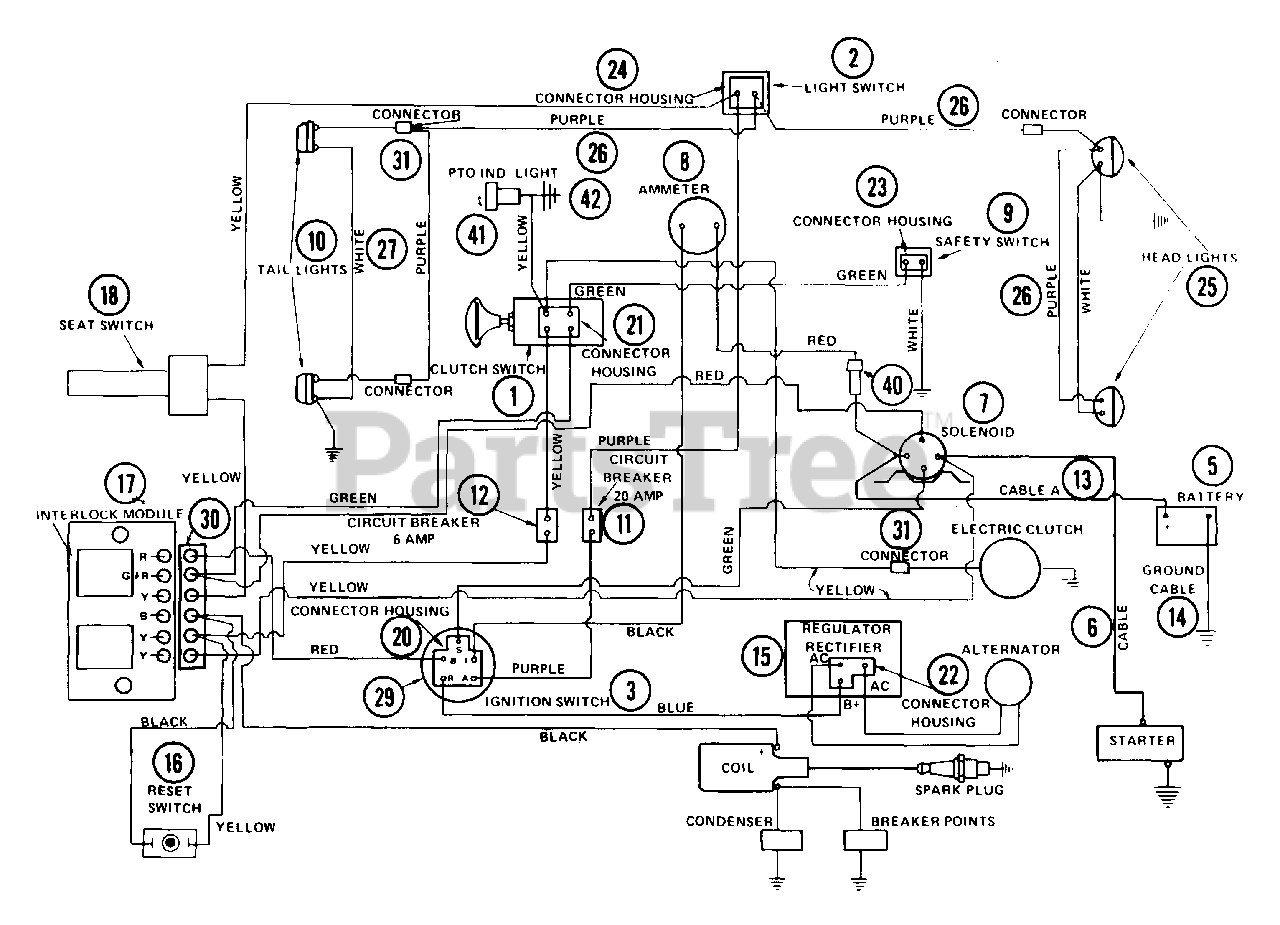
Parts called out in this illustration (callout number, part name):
1	CLUTCH SWITCH
2	LIGHT SWITCH
3	IGNITION SWITCH
5	BATTERY
6	GROUND CABLE .31X22.00X.31
7	SOLENOID
8	AMMETER
9	SAFETY SWITCH
10	TAIL LIGHT
11	CIRCUIT BREAKER
12	CIRCUIT BREAKER
14	GROUND CABLE
17	INTERLOCK MODULE
18	SWITCH SEAT
20	CONNECTOR HOUSING
21	CONNECTOR
22	CONNECTOR
23	CONNECTOR
24	CONNECTOR
25	HEAD LIGHT
26	HEAD LIGHT HARNESS
27	TAIL LIGHT HARNESS
29	DASH HARNESS
30	INTERLOCK MODULE HARNESS
31	WIRE CONNECTOR
40	STD, 30A SAE FUSE
41	PTO INDICATOR LIGHT
41	LAMP
